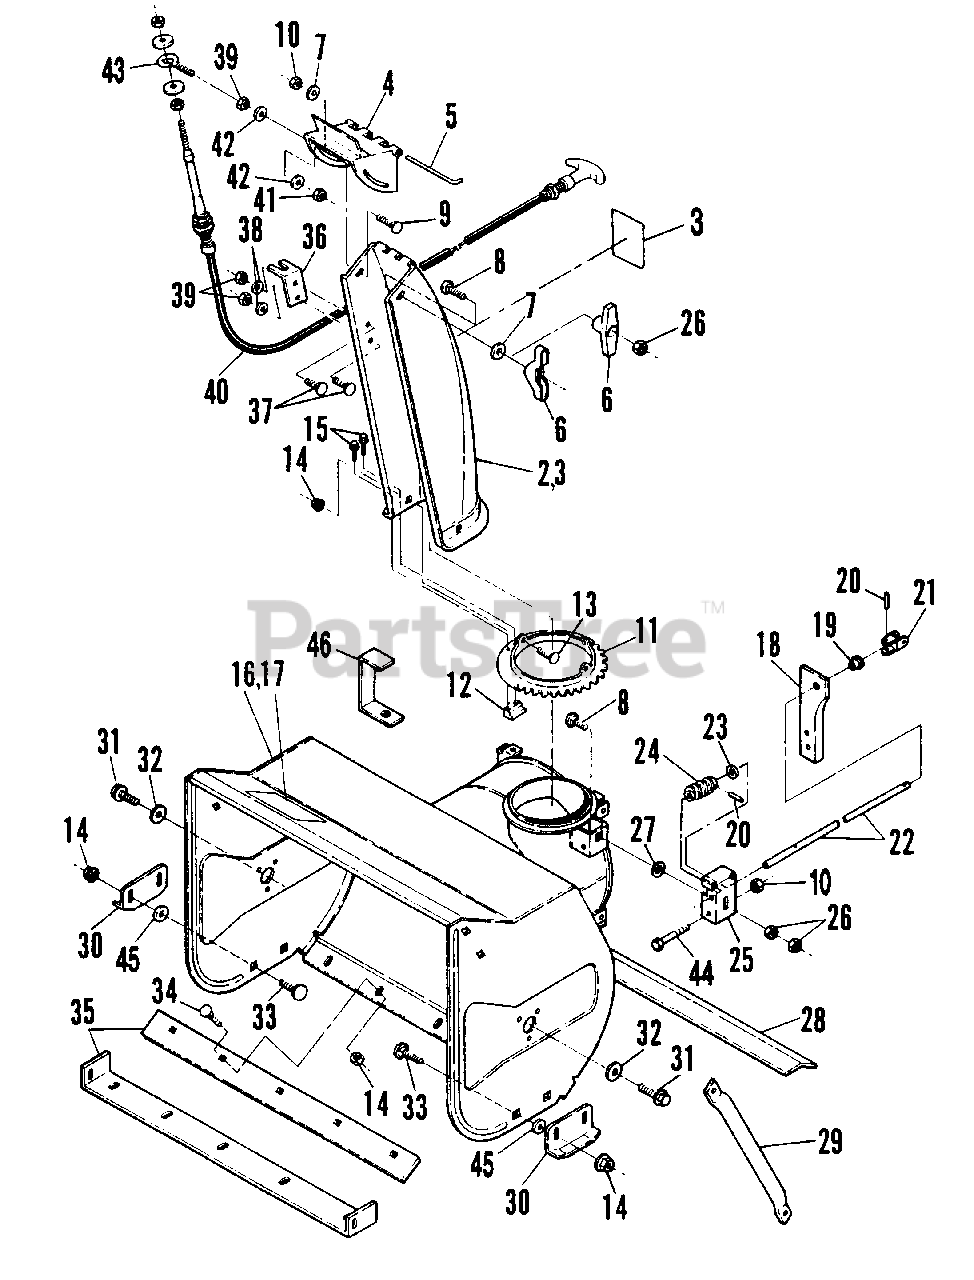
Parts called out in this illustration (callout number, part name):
2	CHUTE, Discharge
3	DECAL, Hand Danger
4	DEFLECTOR, Discharge
5	PIN, Hinge
6	NUT, 5/16-18 Wing
7	WASHER, 5/16 Flat
8	BOLT, 5/16-18 x 1" Carriage
9	SCREW, 5/16-24 x 3/4" Hex Head Cap
10	NUT, 5/16-24 Hex Center Lock
11	RING, Chute
12	RETAINER
13	BOLT, 5/16-18 x 5/8" Carriage
14	NUT, 5/16-18 Hex Flange Lock
15	SCREW, #10-24 x 5/8" Hex Head Cap
16	ASSEMBLY, 24" Blower
17	DECAL, Danger Rotating Auger
18	BRACKET, Worm Shaft Support
19	BUSHING
20	PIN, 1/8 x 3/4" Roll
21	CONNECTOR
22	SHAFT, Worm
23	WASHER, 13/32 Spring
24	WORM
25	BRACKET, Worm Shaft
26	NUT, 5/16-18 Hex
27	RETAINER, 5/16 Bolt
28	BAR, Stiffener
29	BRACE, Side
30	SHOE, Skid
31	SCREW, 3/8-16 x 3/4" Self-Tapping
32	WASHER, 3/8" Flat
33	BOLT, 5/16-18 x 3/4" Short Neck Carriage
34	BOLT, 5/16-18 x 1/2" Short Neck Carriage
35	BLADE, Scraper
36	BRACKET
37	BOLT, 1/4-20 x 1/2" Short Neck Carriage
38	WASHER, 1/4 Internal Tooth Lock
39	NUT, 1/4-20 Hex
40	CABLE, Control
41	NUT, 1/4-20 Hex Center Lock
42	WASHER, 1/4 Flat
43	BOLT, 1/4-20 x 1-1/2" Eye
44	SCREW, 5/16-24 x 2-1/2" Hex Head Cap
45	WASHER, 5/16 Flat
46	GUIDE, Cable
